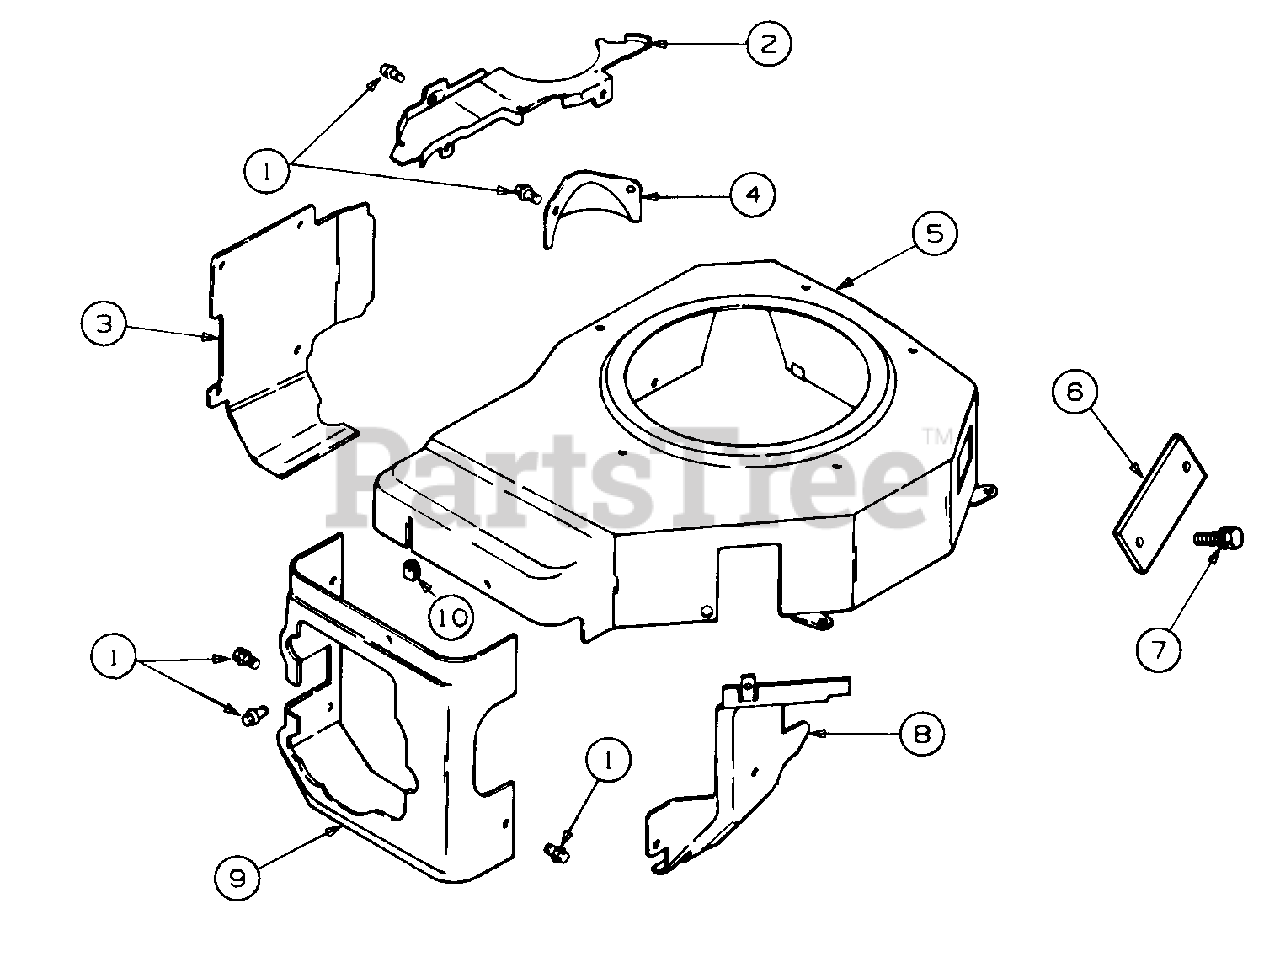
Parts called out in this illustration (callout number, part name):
1	Screw, Mounting, M5 X 0.8 X 10
2	Plate, Blower Housing
3	Baffle, Cylinder Barrel
4	Cover, Starter
5	Housing, Blower
6	Cover, Reg-Rect
7	Screw, Hex Flange, M6 X 1.0 X 16
8	Baffle, Carburetor
9	Baffle, Cylinder Head
10	Grommet, Blower Housing
